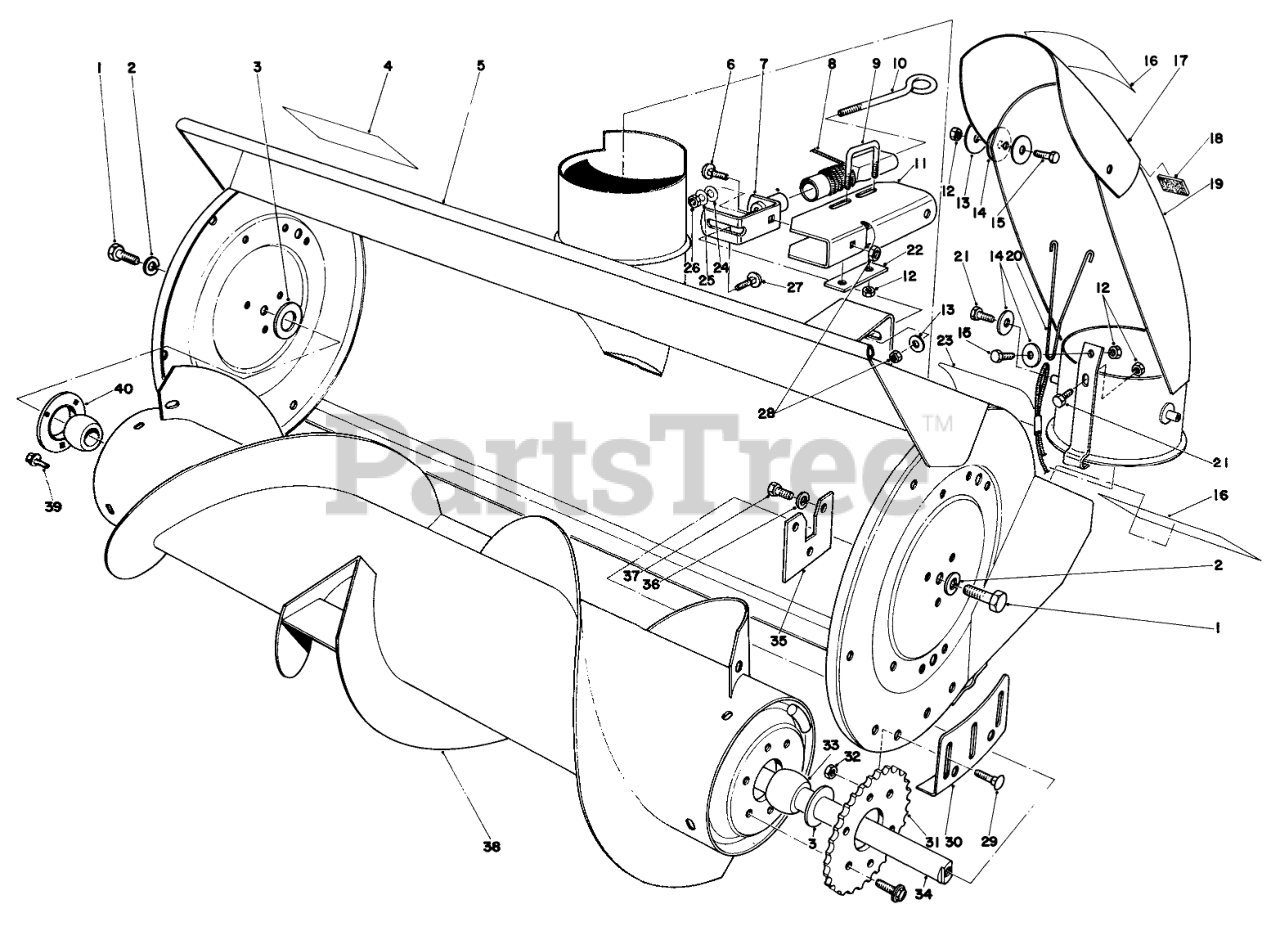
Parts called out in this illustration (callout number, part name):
1	SCREW-HH
2	WASHER-LOCK
3	Spring
4	DECAL
5	Header (Incl. Ref. #16 & 23)
6	SCREW-CARR
7	Bracket & Tube
8	Cable & Tube
9	U-Bolt
10	Eye Bolt
11	Shroud-Stack Drive
12	NUT-HEX, SIDE DEFORM
13	WASHER
14	Washer
15	SCREW-HH
16	Decal-Warning
17	Deflector (Incl. Ref. #16)
18	Molding-Deflector
19	Deflector Elbow
20	Hook-Lift Spring
21	SCREW-HH
22	Strap-Friction
23	CAUTION DECAL
24	WASHER-FLAT
25	Spring Washer
26	NUT-LOCK, CONE
27	BOLT-CARR
28	NUT-KEPS
29	Bolt
30	Skidshoe
31	Sprocket-Auger Drive
32	NUT-KEPS
33	AUGER SHAFT BRG
34	Shaft-Auger
35	Plate-Auger Mounting
36	WASHER-LOCK
37	SCREW-HH
38	Auger Assembly
39	Screw-Cap Hex. Hd.
40	Flangette
